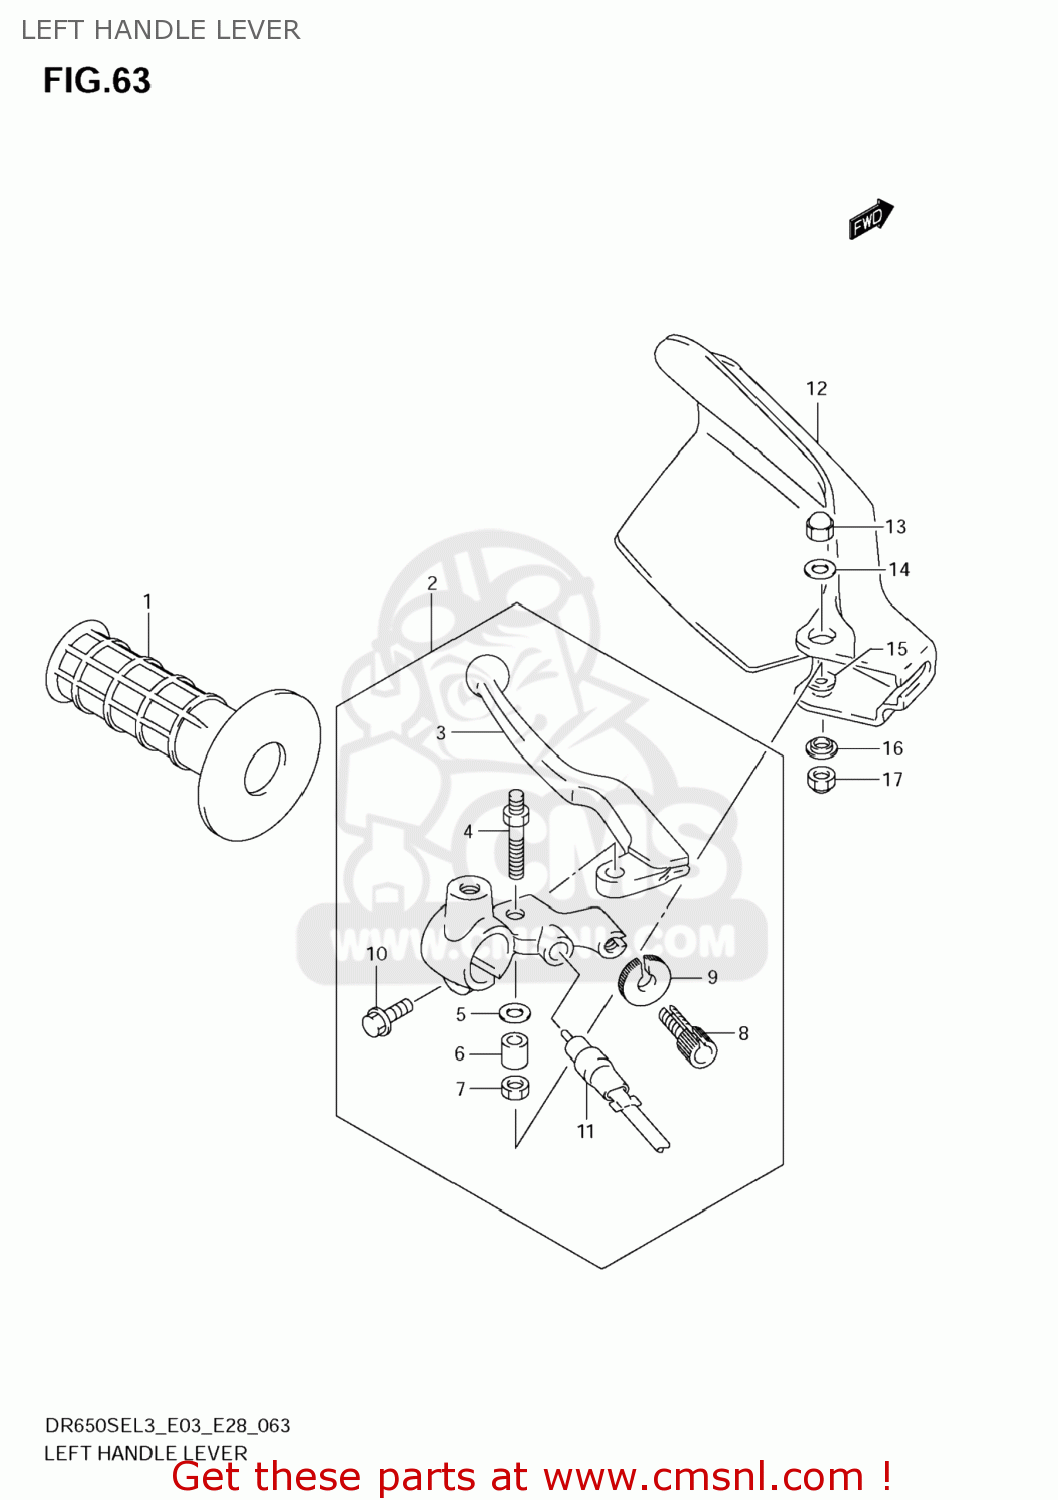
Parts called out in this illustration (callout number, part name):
1	GRIP,L
2	LEVER ASSY,CLUTCH
3	LEVER,CLUTCH
4	BOLT,PIVOT
5	WASHER
6	SPACER
7	NUT
8	ADJUSTER,WIRE
9	NUT,LOCK
10	BOLT
11	SWITCH ASSY,CLUTCH
12	COVER,KNUCKLE,L
13	NUT
14	WASHER(6.5X20X1.6)
15	WASHER(6.5X16X1.2)
16	WASHER
17	NUT
